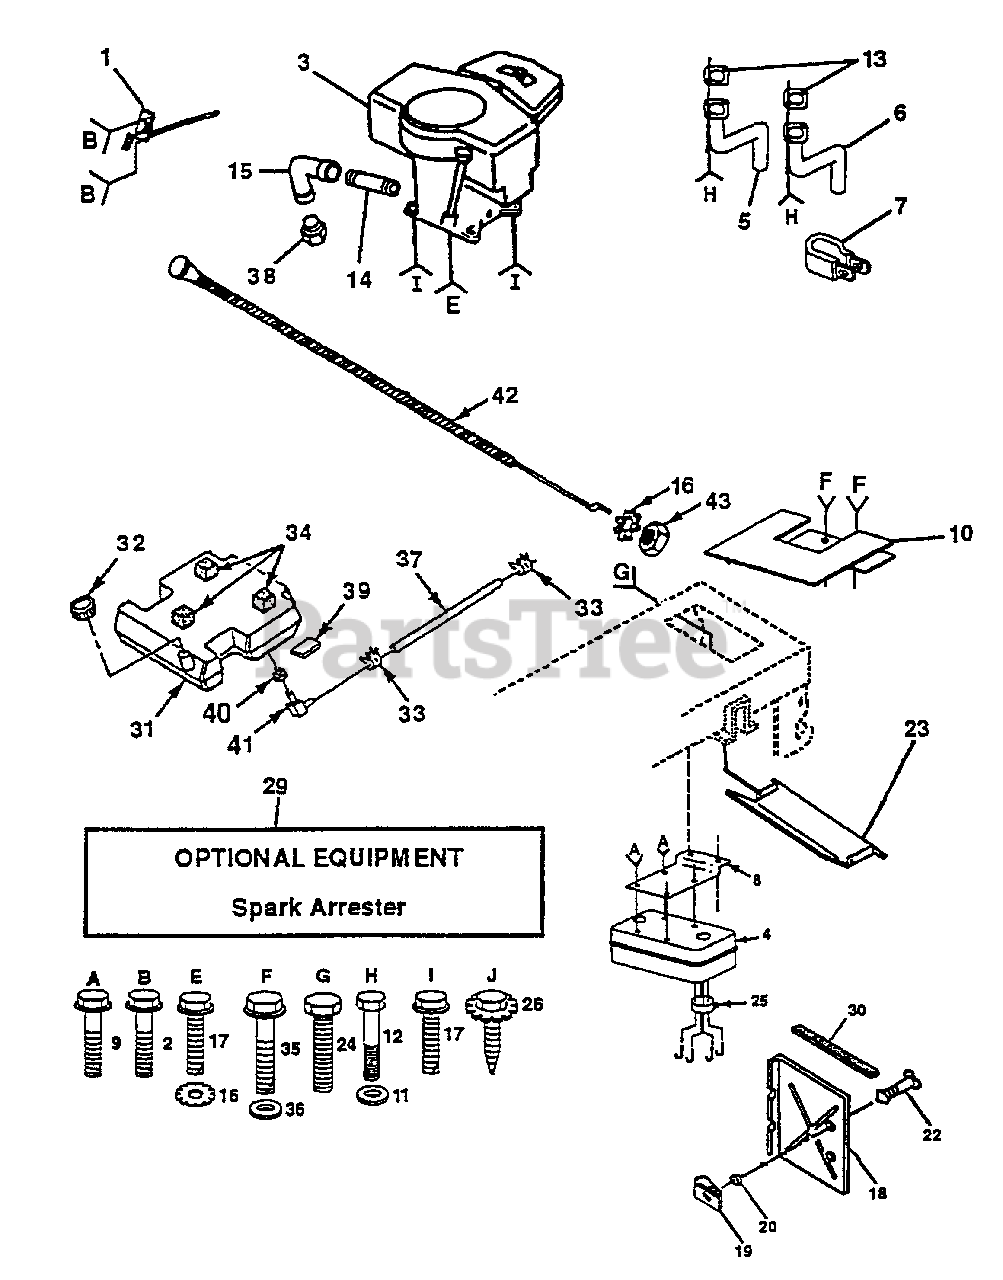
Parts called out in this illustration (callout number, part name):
1	Control RH Blk Fig 44 75
2	Screw Hex Thd Cut 1/4-20x5/8 T
4	Muffler LT B&S
5	Tube Manifold LH
6	Tube Manifold RH
7	Clamp Tube Double Engine
8	Bracket Muffler Mounting
9	Screw Hex Wsh Thd Cut 1/4-20
10	Shield Heat LT
13	Muffler Gasket
14	Nipple Pipe 3/8 Npt X 4-1/2"
15	Elbow Std 90 Degree 3/8-18 Npt
16	Washer Lock Ext Tooth 3/8
17	Screw Thdrol 3/8-16 x 1-1/4
18	Shield Heat Electric
19	Receptacle 1/4 Turn
20	Retainer 1/4 Turn
22	Stud 1/4 Turn
23	Shield Heat Browning LT/YT
24	Screw Tap Hex #10-24unc X 1/2
25	Deflector Muffler
26	Screw Spiderloc Hex Hd #8 x 1/2
29	Kit Spark Arrestor (Flat Scrn)
30	Foam Strip 18"
31	Tank Fuel 3 50 Rear
32	Cap Asm Fuel W/sym Vented
33	Clamp Hose Blk
34	Pad, Spacer
35	Screw Thdrol 5/16-18 x 3/4
36	Washer 13/32 x 1-1/4 x 12 Ga.
37	Line Fuel 54"
38	Plug Oil Drain
39	Pad, Idler
40	Bushing
41	Stem Tank Fuel
42	Choke Control
43	Nut, Fin Hex 3/8-24 Unf
